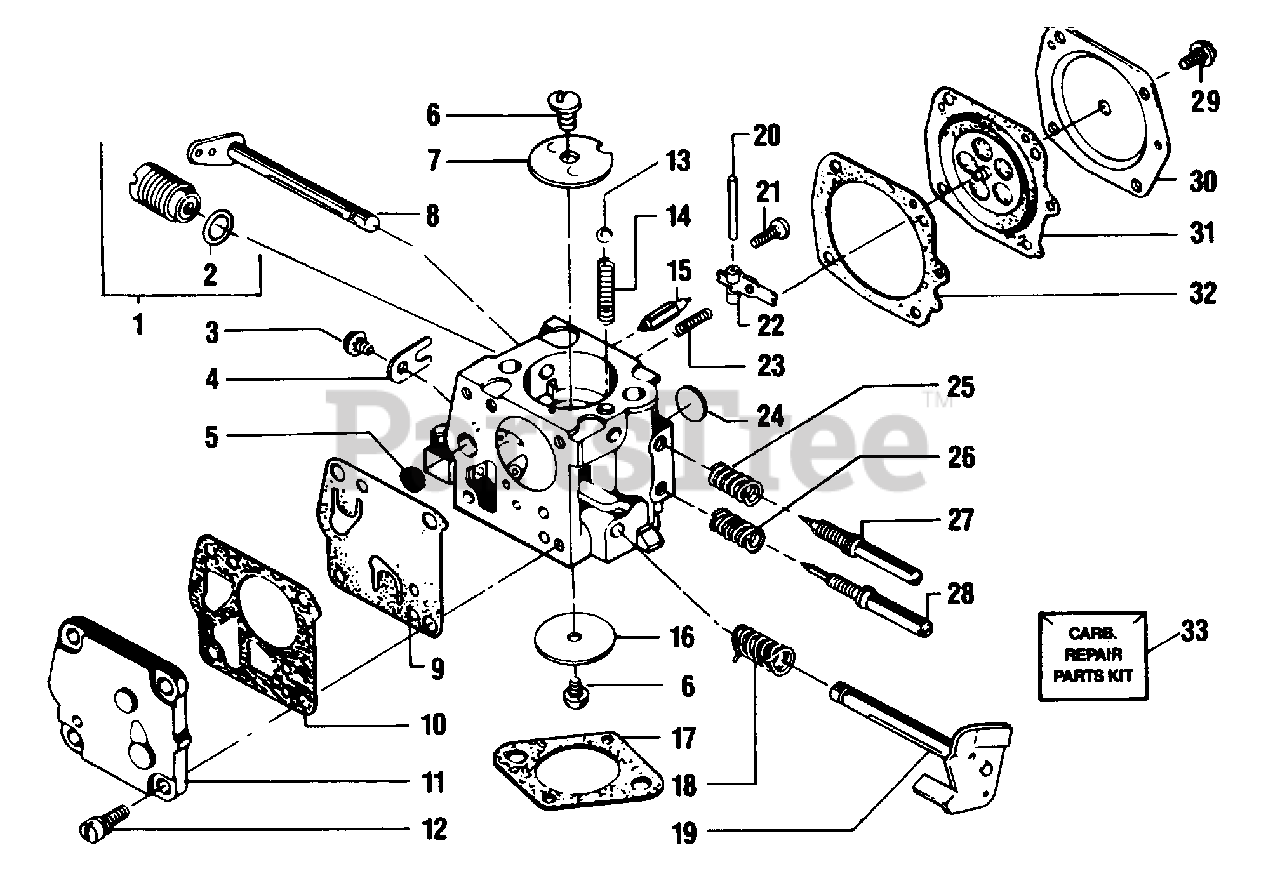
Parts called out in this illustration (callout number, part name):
1	Governor Valve Assembly (incl. #2)
2	Gasket-Governor Valve
3	Screw-Throttle Shaft Clip Retainer
4	Clip-Throttle Shaft
5	Inlet Screen
6	Shutter Screw & Lockwasher
7	Choke Shutter
8	Choke Shaft & Lever
9	Fuel Pump Diaphragm
10	Fuel Pump Gasket
11	Fuel Pump Cover
12	Screw and Lockwasher-Fuel Pump Cover Retainer
13	Choke Friction Ball
14	Choke Friction Spring
15	Needle-Inlet
16	Throttle Shutter
18	Spring-Throttle Shaft Return
19	Throttle Shaft & Lever
20	Pin-Inlet Pinion
21	Screw-Inlet Pinion Pin Retainer
22	Lever-Inlet Control
23	Spring-Inlet Tension
24	Plug-Body Channel Welch (Large)
25	Spring-High Speed Mixture Spring (Blue)
26	Spring-Idle Mixture Screw (Yellow)
27	HIGH SPEED SCREW
28	Screw-Idle Mixture
29	Screw & Lockwasher-Diaphragm
30	Cover-Diaphragm (Dana part number)
31	Diaphragm
32	Gasket-Diaphragm
33	Carb.- Repair Parts Kit (Inc. 5,9,10,15, 17,22,24,31,32)
